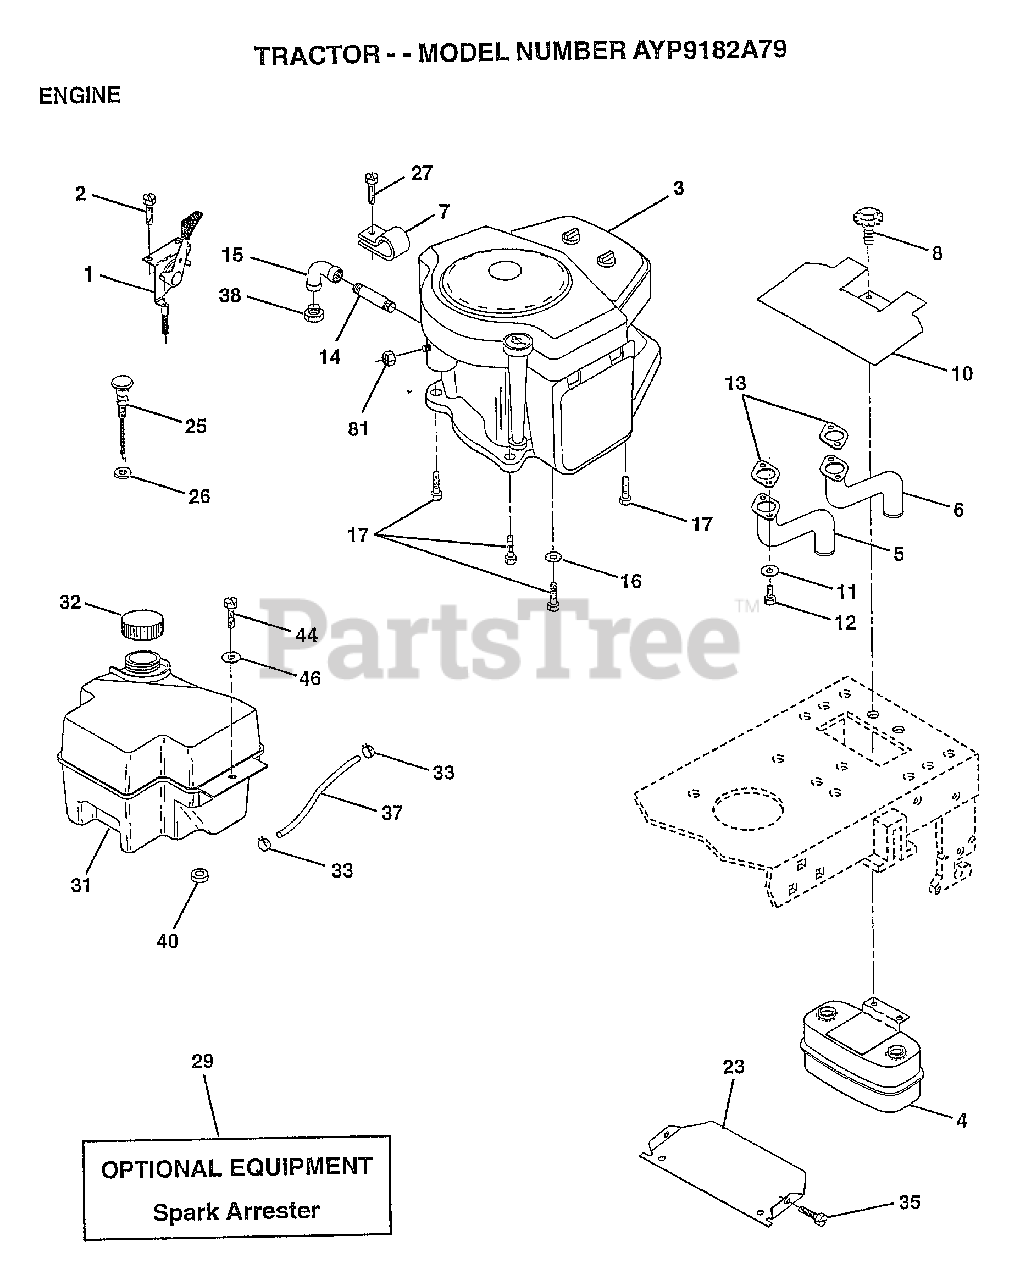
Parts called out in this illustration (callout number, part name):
1	CONTROL THRT 35.5
2	SCREW LT
3	ENGINE, BRIGGS
4	MUFFLER.TW.LOTONE
5	EXHAUST.B&S.18.LH
6	EXHAUST.B&S.18.RH
7	CLAMP.TUBE.DBL.EN
8	BOLT.5/16-18.UNC
10	SHIELD.HEAT.
11	LOCKWASHER
13	GASKET MUFFLER
14	PIPE NIPPLE LT
15	ELBOW
16	LOCKWASHER
17	SCREW LT
23	SHIELD-HEAT
25	CONTROL.CHOKE.37
26	"NUT,KEPS 3/8-24IM"
27	"SCREW-TT,10-32 FL"
32	CAP ASM FUEL
33	HOSE CLAMP
35	SCREW
37	LINE FUEL
44	SCREW HEX CRT
46	WASHER
81	NUT
